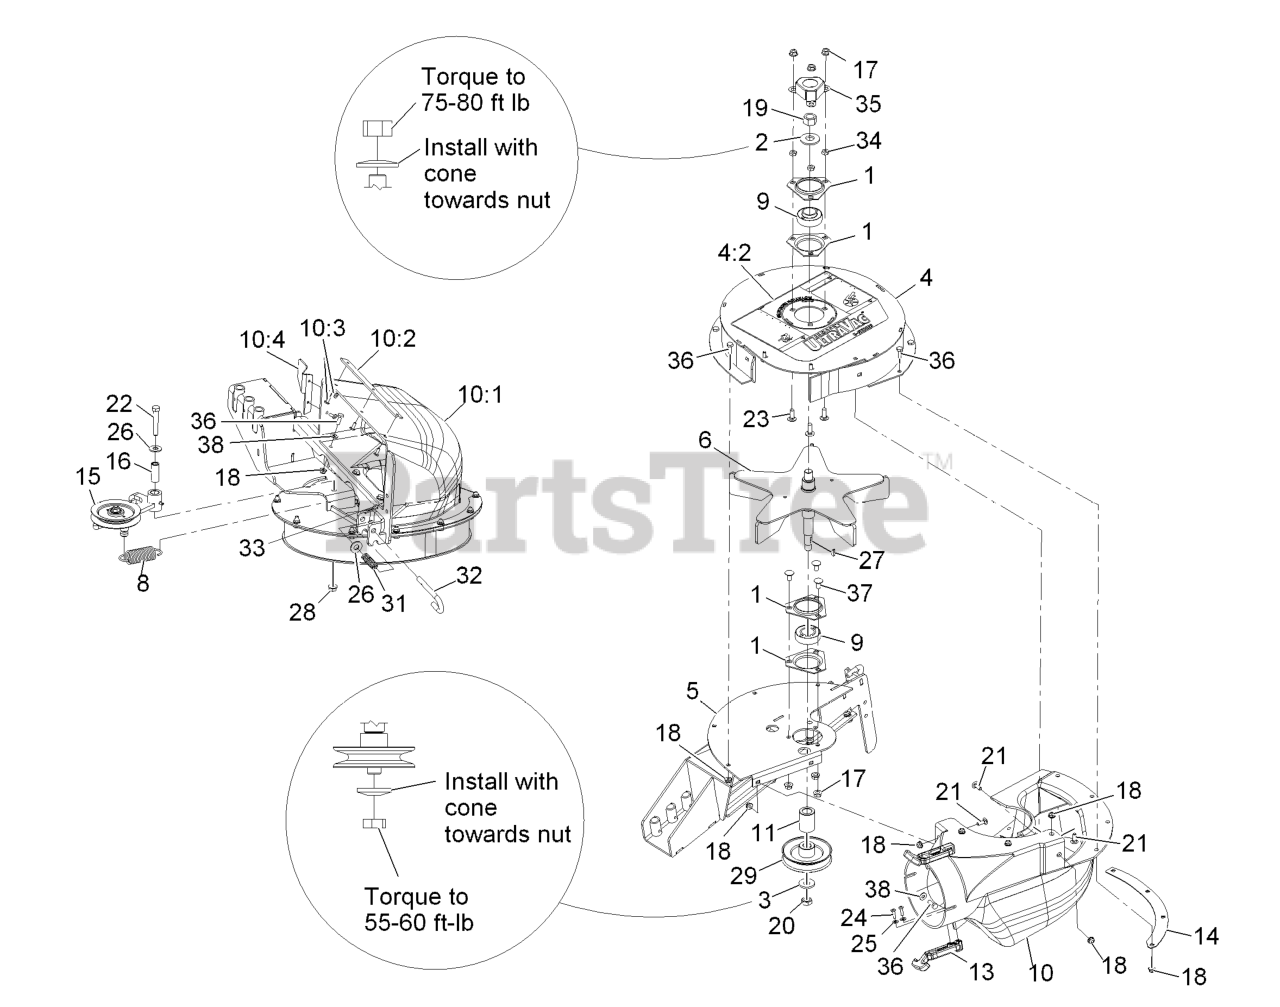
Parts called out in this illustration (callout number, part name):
1	HOUSING-FLANGE
2	WASHER-SPRING
3	WASHER-SPRING
4	UPPER HOUSING W/DECAL
4:2	DECAL-BLOWER WARNING
6	IMPELLER
8	SPRING-IDLER
9	BEARING
10:1	CHUTE-BLOWER, SMALL
10:2	PLATE-REINFORCEMENT
10:3	RIVET-BLIND
13	LATCH-RUBBER
14	PLATE-BACKING
15	Asm, Idler
16	BUSHING
19	NUT-HEX
20	NUT-JAM
21	BOLT-CARR
22	SCREW-HH
23	BOLT-CARR
24	SCREW-PPH
25	WASHER-FLAT
26	WASHER-FLAT
27	KEY-WOODRUFF
28	NUT-HHF, WHIZ
29	SHEAVE-BLOWER
31	SPRING-COMPRESSION
32	PIN-LATCH
33	PIN-HAIR
34	NUT-JAM
35	COVER-NUT
36	SCREW-HH
37	SCREW-CARR
38	WASHER-FLAT
